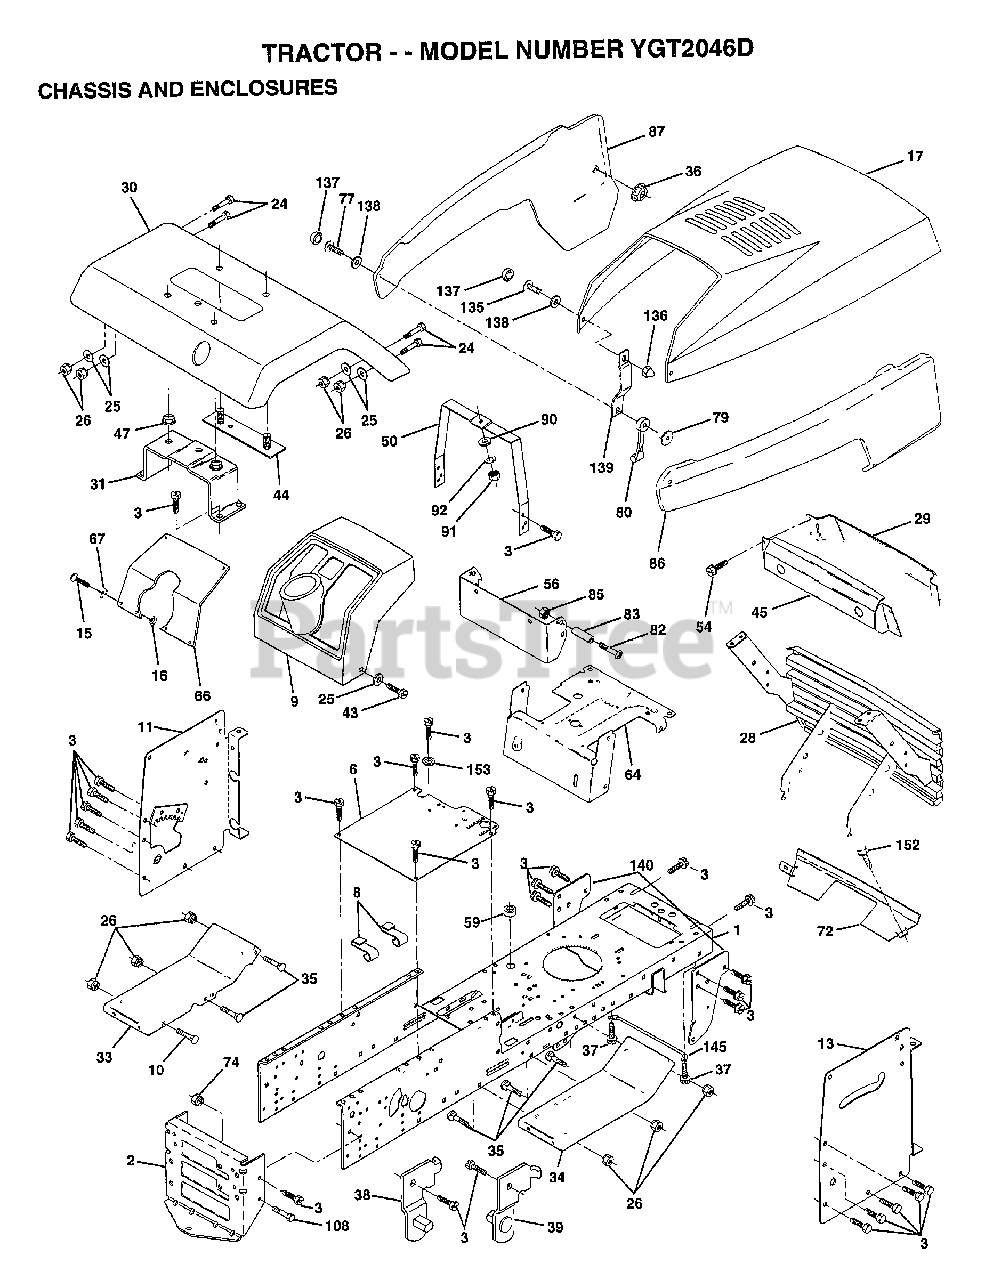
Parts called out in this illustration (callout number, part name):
1	CHASSIS.STAMPING
3	SCREW
6	SADDLE
8	"CLIP,INSULATOR"
9	DASHBOARD BLACK
11	DASHBRD.PANEL.LH
13	DASHBRD.PANEL.RH
15	SCREW
17	"HOOD, YARD PRO"
24	BOLT
25	WASHER
26	NUT
28	GRILLE ASM PNT
29	LENS.BAR.CLEAR
30	"FENDER WS,FTK"
31	BRKT.ASM.FENDER
33	FOOTREST PNT LH
34	FOOTREST.RH.LT/GT
35	BOLT
36	PAL NUT LT
37	SCREW LT
38	BRACKET ASM LH
39	BRACKET ASM RH
43	SCREW
44	STRAP ASM FENDER
45	BEZEL.ASM.
47	NUT-PUSH YT
50	DASH.SUPT.YP/HUSQ
54	SCREW.HEX.WS.HD
56	EXT DASH LTYT
64	DASH.LOWER.LT
67	WASHER
77	SCREW
79	WELDNUT
80	HOOD LATCH T
82	SCREW
83	SPACER LT
86	"PANEL ASM SIDE,RH"
87	"PANEL ASM-SIDE,LH"
90	WASHER PM
92	LOCKWASHER
135	SCREW.10-24X3/8.
136	ACORN NUT RB
137	SNAP CAP LT
138	WASHER LT
139	BKT.SPT.HOOD/PANL
140	BRKT SUSPENSION
145	"ROD POVOT,CHASSIS"
152	SCREW
153	WASHER GT
